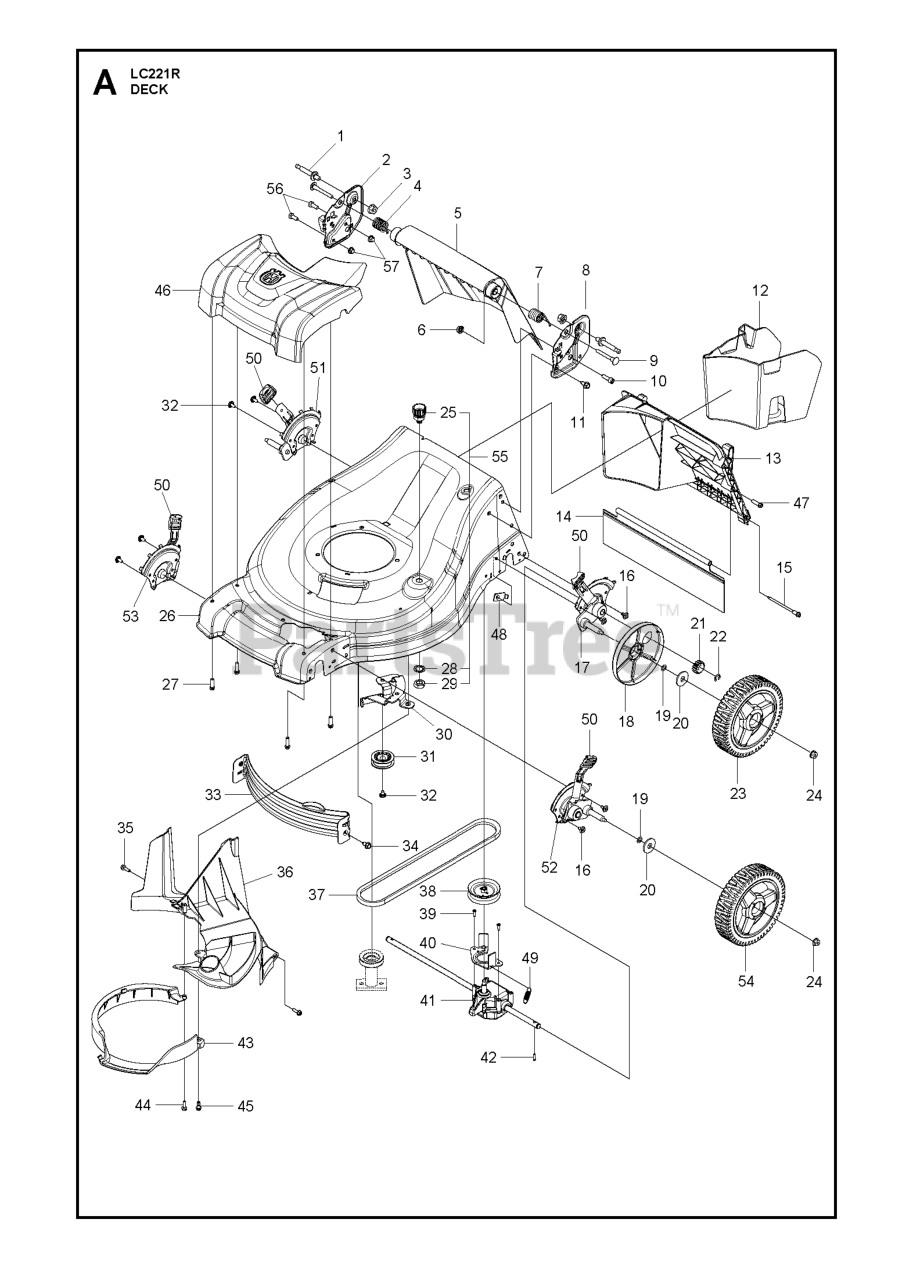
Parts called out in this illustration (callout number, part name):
1	BOLT.HAND.PIVOT.3125-18.21EFF
2	BRACKET.HANDLE.ADJ.21EF.RH.498
3	NUT.FLANGE.SERRAT.3125-18.5625
4	SPRING.RH.DOOR.21 EFF
5	DOOR REAR, 21IN EFF GRAY MS-49
6	NUT.FLANGED.3/8-16.ZINC
7	SPRING.LH.DOOR.21 EFF
8	BRACKET.HANDLE.ADJ.21EF.LH.498
9	BOLT.DOOR.PIVOT..375-16.21EFF
10	SCREW.HI-LO,5/16-14 X T-45
11	BOLT.5/16HEX.WHS.HD
12	PLUG.MULCH.21 EFF
13	INSERT.REAR.21 EFF
14	SKIRT.REAR.21 EFF
15	SCREW.HI-LO.5/16-14 X 4.10
16	SCREW
17	ADJUSTER.4PT.21EFF.RF/LR.BLK
18	COVER.DUST.WHEEL.INNER.WALK
19	O-RING..070X.487.NEOPRENE
20	WASHER FLUT
21	PINIION.14.TOOTH.RGD
22	E-RING 7/16 RE
23	WHEEL.8X1.75.3SPK.RAD3.GREY
24	NUT.HEX.FLANGE.3/8-16.LO(3 2)
25	FITTING, HOSE, WATER WASHOUT
26	KIT.HSG.21EFF.AWD.WO.668.CE SY
27	SCREW.HI-LO. 5/16 X 1.00
28	WASHER.LOCK.INTERNAL.TOOTH
29	LOCKNUT.HEX.WITH.O-RING
30	BRACKET.IDLER.RWD.BZP
31	PULLEY.RWD.IDLER.DBL SEAL
32	SCREW
33	BAFFLE.FRONT.21 EFF
34	BOLT.5/16HEX.WHS.HD
35	SCREW.HI-LO.13-16X.750.375XDRV
36	COVER.BELT/REAR BAFFLE.21 EFF
37	BELT.21EFF.RWD
38	PULLEY.DRIVE.SM.AWD/RWD
39	SCREW
40	BRACKET.TRANS.BELTKEEP.21 RWD
41	TRANSMISSION.AWD.REAR.21EFF
42	PAWL, DRIVE
43	RING.STRIPPER.21 EFF
44	SCREW.HI-LO.13-16X.750.375XDRV
45	BOLT SHOULDER_1/4-20_TRILOB
46	COVER.DR.FULL.HUSQ.21EFF.RWD
47	SCREW.HI-LO,5/16-14 X T-45
48	STRAP.PLATE ATTACH.21 EFF.GLV
49	SPRING.RETURN.AUTO.
50	SELECTOR KNOB
51	ADJUSTER.4PT.21EFF.LF/RR.BLK
52	ADJUSTER.4PT.21EFF.LF/RR.BU.BK
53	ADJUSTER.4PT.21EFF.RF/LR.BU.BK
54	WHEEL & TIRES ASSY, FRONT
55	KIT.WASH-OUT.PORT
56	BOLT.FIN.HEX.5/16-18X3/4
57	NUTNYLOK.FLRANGE.5/16-18
